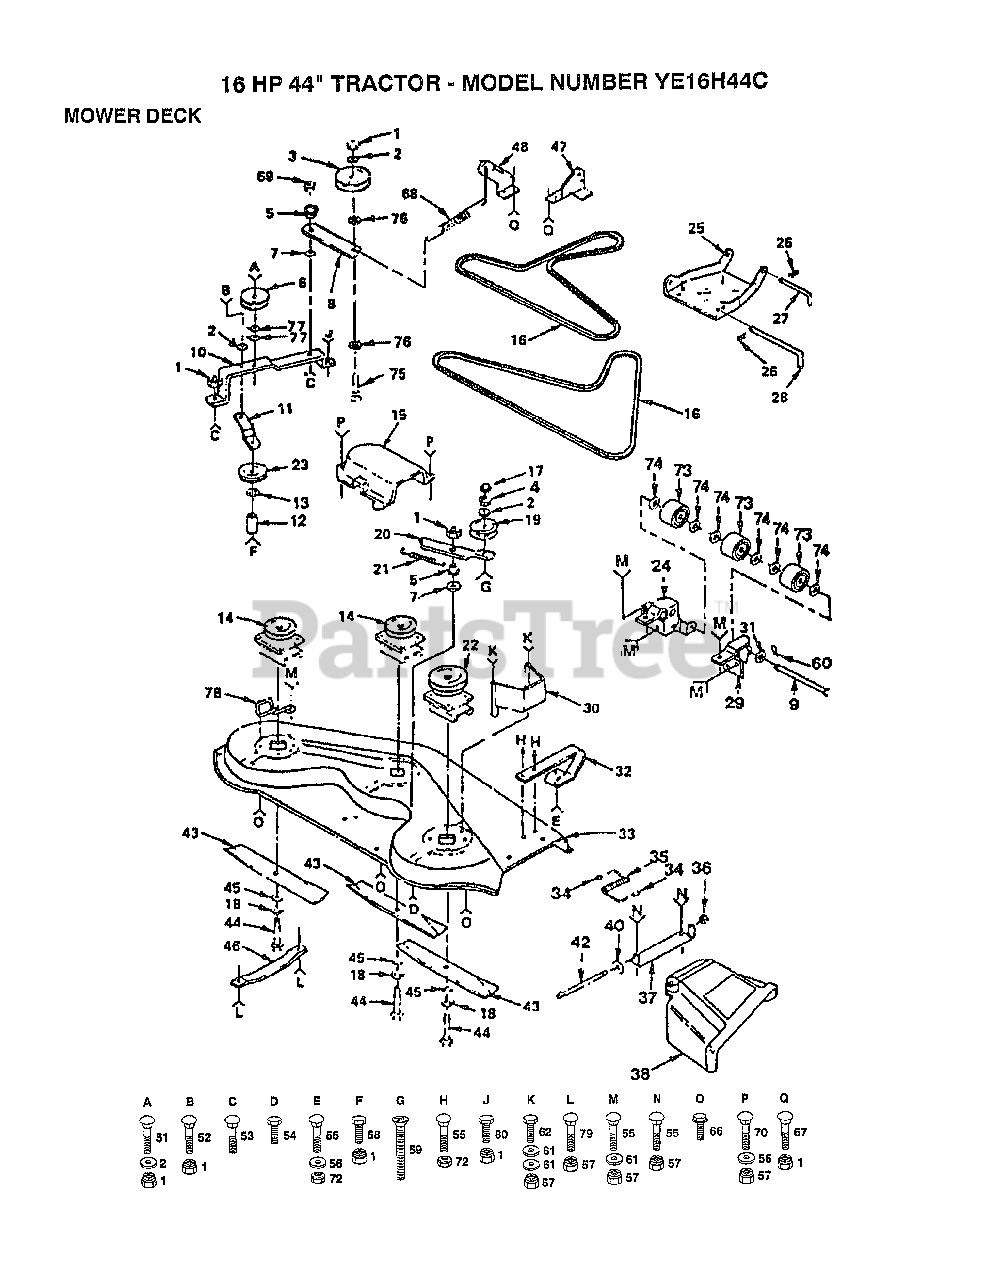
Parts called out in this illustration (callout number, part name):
2	WASHER
3	PULLEY IDLER
4	LOCKWASHER
5	SPACER RETAINER
6	IDLER-INSIDE T
7	"WASHER, WEAR LT"
8	ARM IDLER
9	PIVOT PIN T
10	"SUPPORT YT, BAR"
11	BRACE-IDLER YT
12	SPACER
13	WASHER
15	GUARD YT
16	BELT-V.79.1.MWR
17	NUT.HEX.3/8-16UNC
19	IDLER.FLAT.GTV
20	ARM-IDLER YT
22	JACKSHAFT
23	IDLER-FLAT T
24	BRACKET LH YTH
25	LINK.PARALLEL
26	SPRING.RETAINER
27	"ROD, FRT. PARAL T"
28	HINGE PIN T
29	BRACKET RH YTH
30	GUARD BELT HYT
34	CAP-SLEEVE LT
36	NUT PUSH M
38	DEFLECTOR SHIELD
40	WASHER
42	ROD-HINGE T
44	BOLT.3/8-24X1-1/2
45	WASHER
46	RUNNER-LH M
47	BRKT SUSP REAR RH
48	BRKT SUSP REAR LH
51	BOLT
53	BOLT
55	BOLT
56	WASHER
58	BOLT - HEX 3/8 - 16 X 3
59	SCREW YT
60	COTTER PIN
61	WASHER M
62	BOLT
66	SCREW
67	BOLT
68	"SPRING.EXT.8.5"""
69	LOCKNUT
73	ROLLER T
74	WASHER T
75	BOLT
76	WASHER
77	WASHER
78	BELT RETIANER
79	BOLT
80	BOLT
